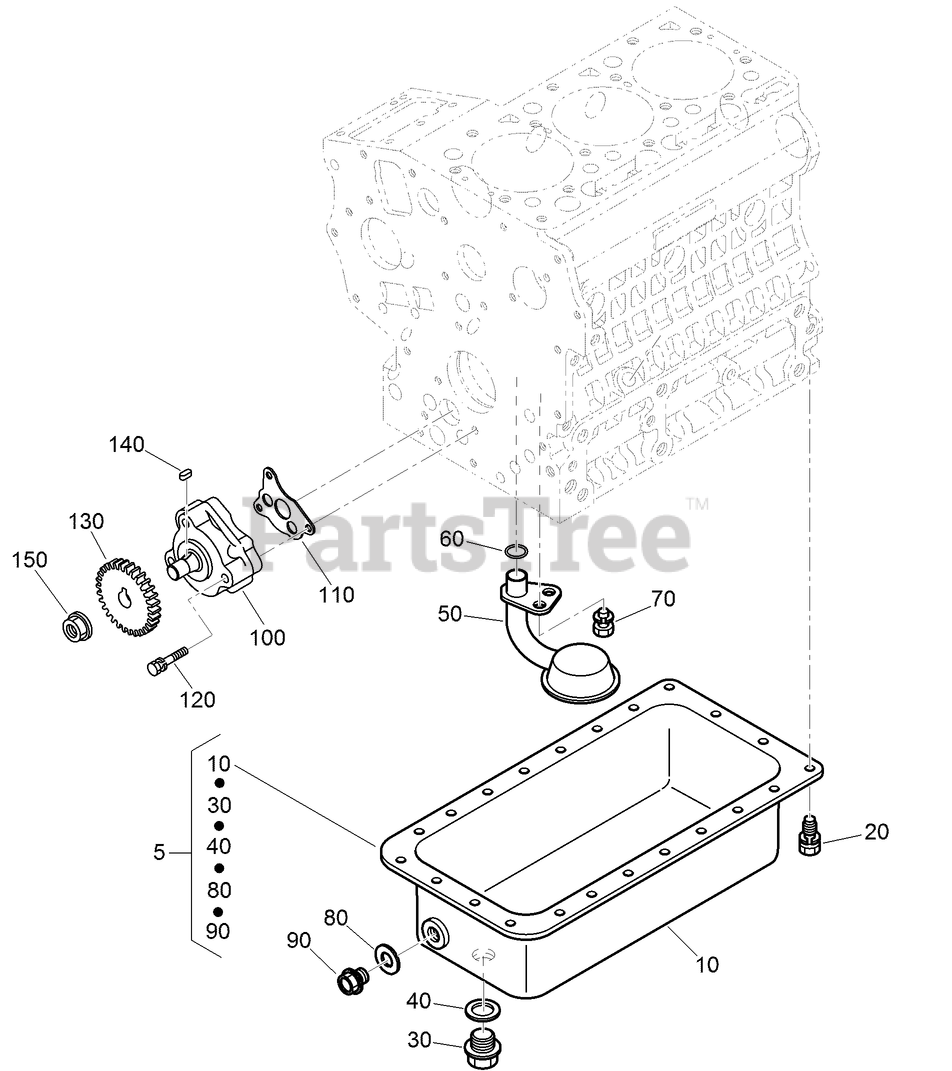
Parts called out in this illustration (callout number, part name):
5	OIL PAN KIT
10	PAN-OIL
30	PLUG-DRAIN
40	GASKET-PAN, OIL
50	STRAINER-PICKUP, OIL
60	O-RING
80	GASKET
90	PLUG-DRAIN
100	OIL PUMP ASM
110	GASKET-PUMP, OIL
130	GEAR-DRIVE, OIL PUMP
140	KEY-FEATHER
150	NUT-FLANGE
